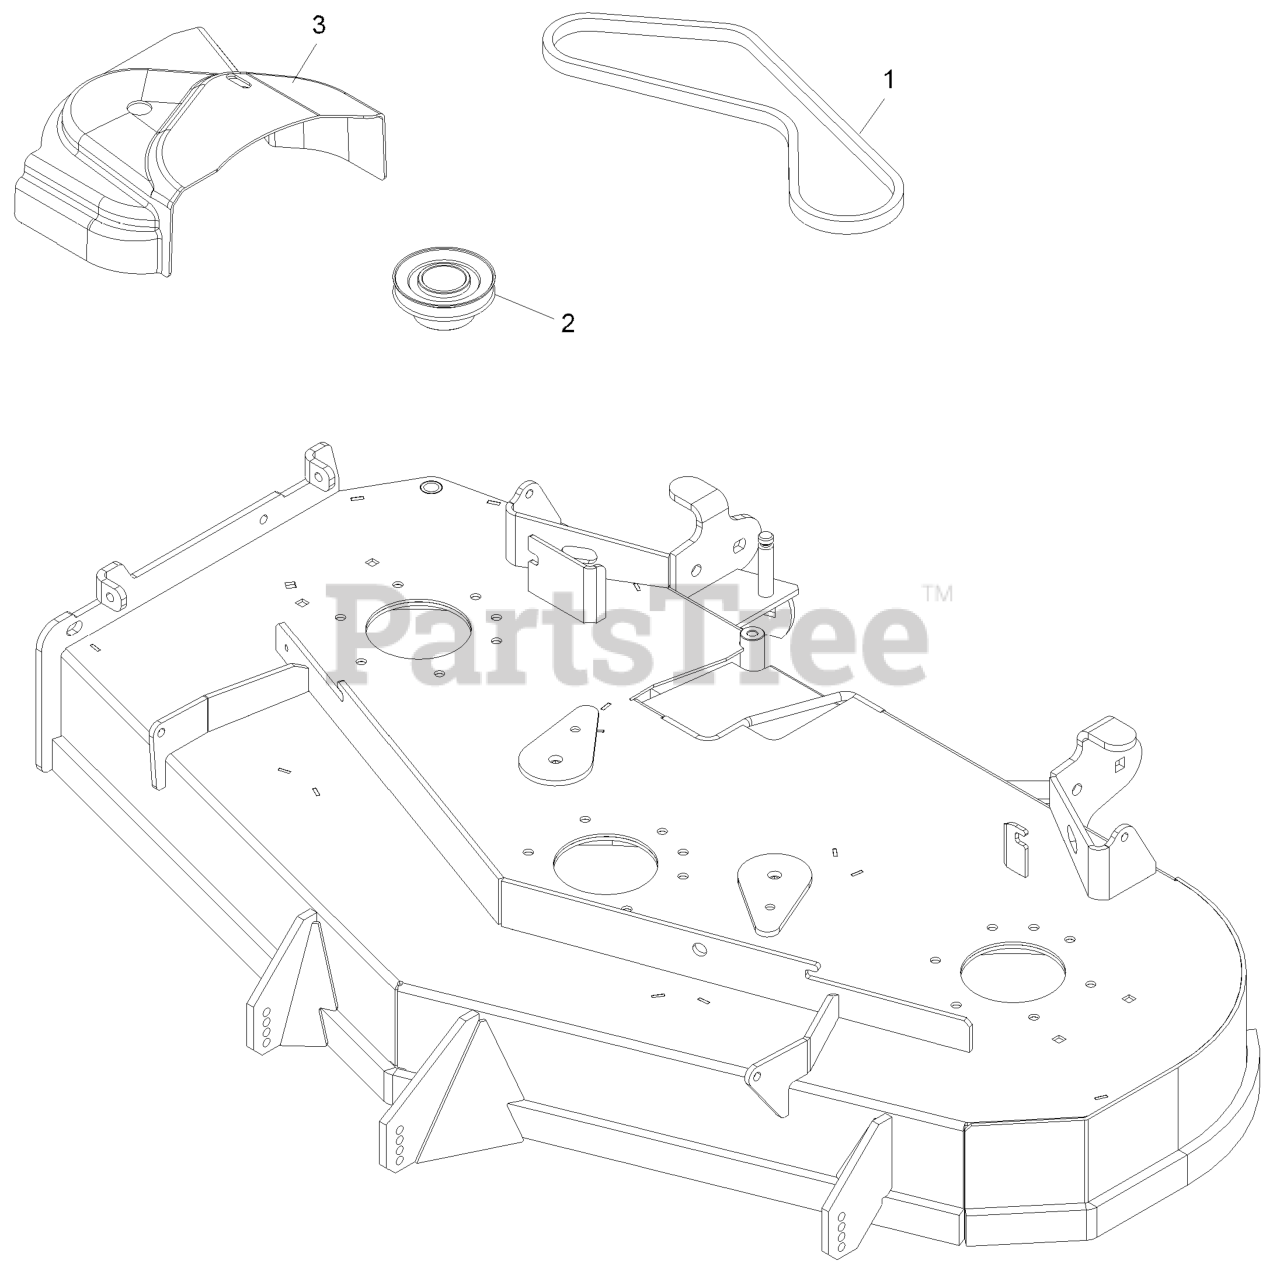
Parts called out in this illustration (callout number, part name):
1	BELT, BLOWER 52"DECK
2	SHEAVE,DRIVE LZUV 526
3	COVER,BELT UV 52
